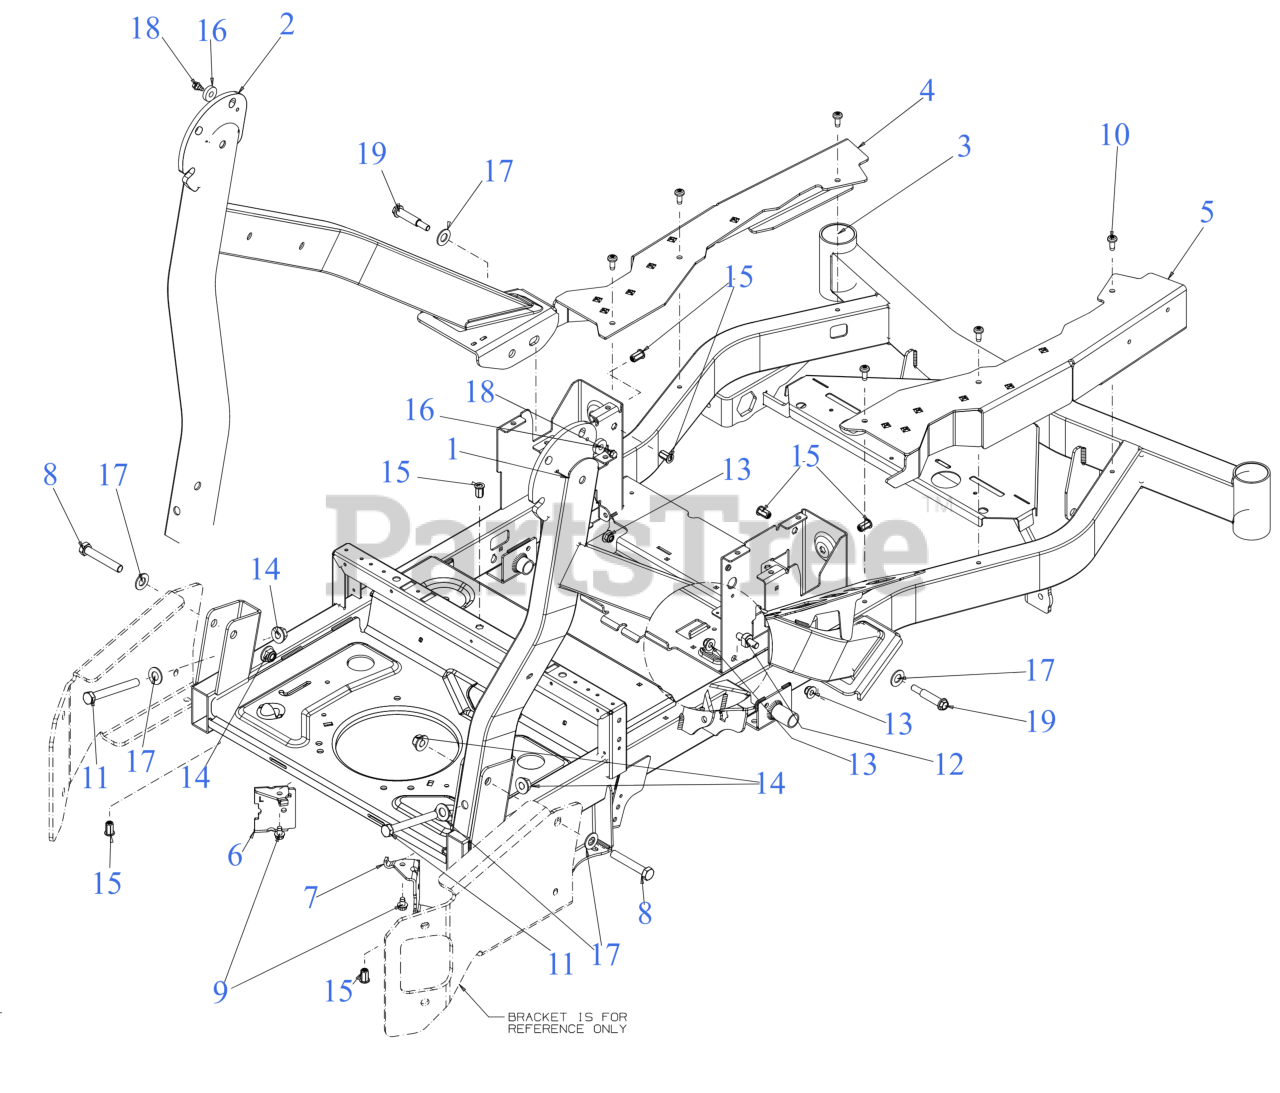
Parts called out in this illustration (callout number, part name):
1	UPPER FRAME (RH)
2	UPPER FRAME (LH)
3	FRAME
4	FRAME COVER (LH)
5	FRAME COVER (RH)
6	TRANSMISSION SUPPORT (LH)
7	TRANSMISSION SUPPORT (RH)
8	SCREW-HEX 1/2-13 x 3.00
9	SCREW 5/16-18 x .500
10	SCREW 5/16-18 X.75
11	HEX CAP SCREW 1/2-13x4.25 GR5
12	SHOULDER STUD
15	NUT RIVET 5/16-18
16	NEOPRENE WASHER BUMPER
17	FLAT WASHER
18	SHOULDER SCREW 1/4-20 x .50
19	SHOULDER SCREW .50x1.75 3/8-16
